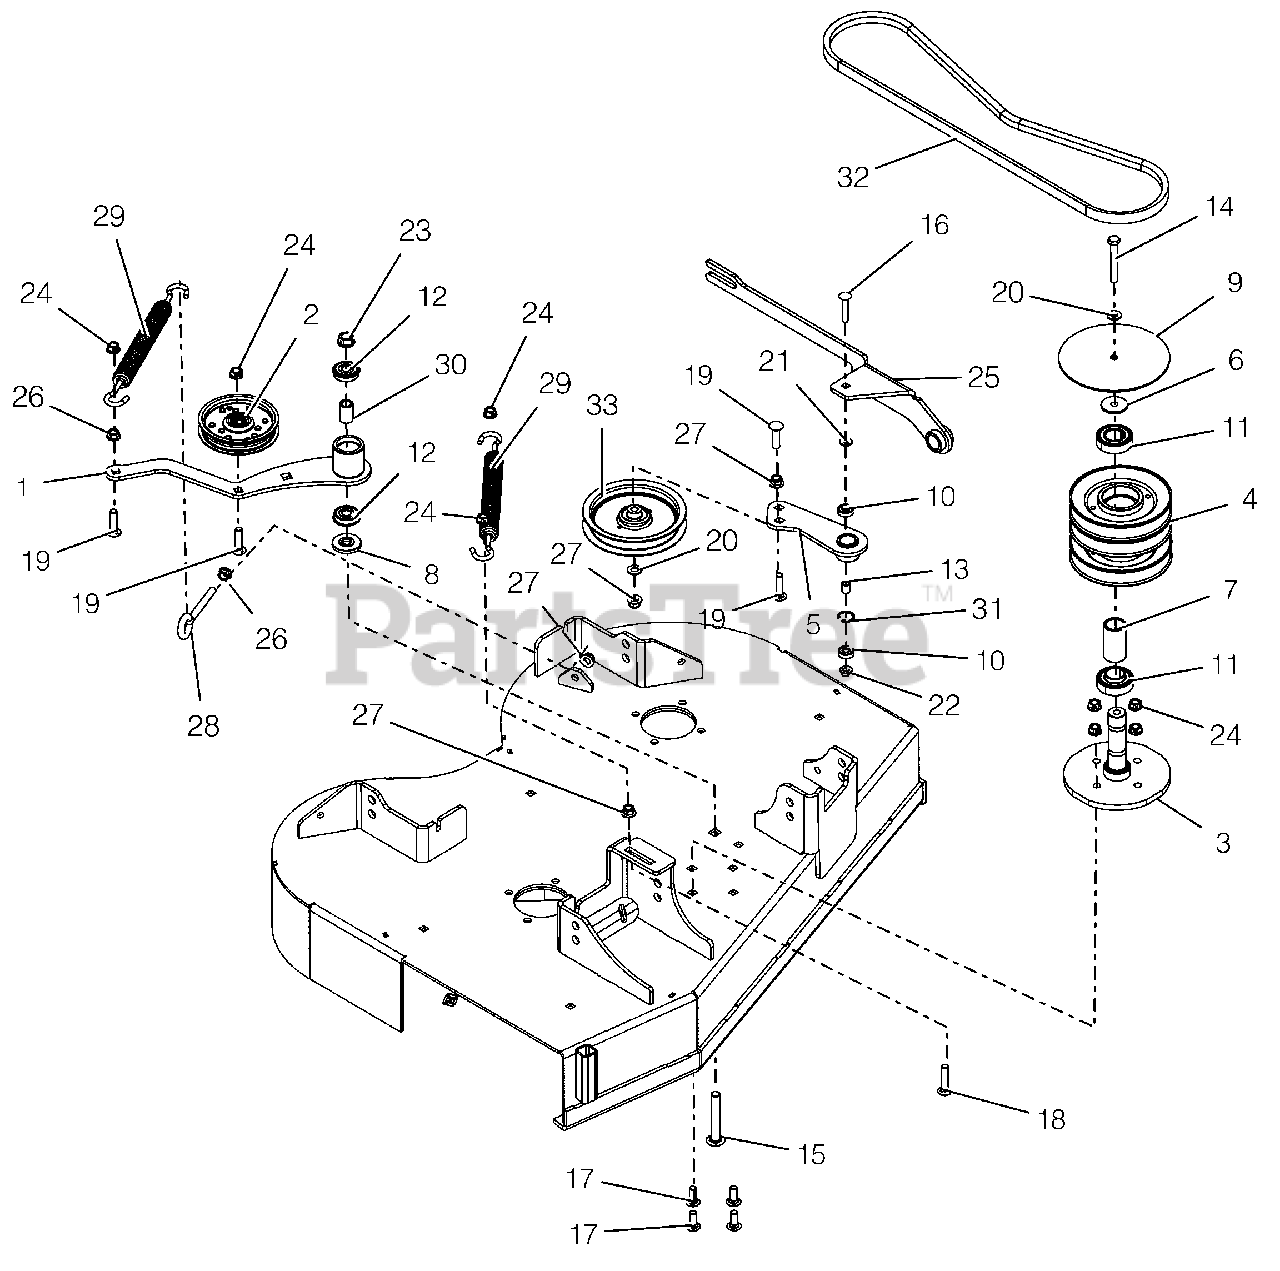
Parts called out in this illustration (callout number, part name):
1	WLDMT, IDLER ARM
2	ASM, 4" IDLER (.75 WIDE)
3	WLDMT, JACKSHAFT SHAFT
4	WLDMT, JACKSHAFT HOUSING
5	WLDMT, DECK IDLER
6	RETAINER, JACKSHAFT SPINDLE
7	SPCR, BEARING SPINDLE
8	SPACER, IDLER ARM
9	PLATE, JACKSHAFT COVER
10	BRG-BALL .315X.866X.276(608)
11	BEARING, RG 1.00X2.0467X.591
12	BRG-BALL .50X1.38X.438 SEALED
13	BSHG-SLV .330X.455X.550
14	BLT-HEX .38-16X2.75 GR8 YWZC
15	BLT,RDHDSQSHNK.50-13X3.25 G5YZ
16	@BLT-RDHDSQNK .31-18X1.75 G5YZ
17	@BLT-RDHDSQNK .38-16X1.00 G5YZ
18	@BLT-RDHDSQNK .38-16X1.75 G5YZ
19	@BLT-RDHDSQNK .38-16X1.50 G5YZ
20	@WSHR-FL-STL.406X.812X.065 YWZ
21	@WSHR-FL-STL.344X.688X.065YWZC
22	@NUT-LK-CTR-FLG .31-18 YZ GR F
23	NUT-LK-CTR-FLG .50-13 YWZC
24	NUT-LK-CTR-FLG .38-16 YWZC
25	WLDMT, PIVOTING IDLER
26	@NUT-SPNLK-FLG .375-16 YWZC
27	@NUT-LK-NYL-FLG .38-16 YWZC
28	BOLT,EYE .38-16X4.50,.75"EYE
29	SPRING, EXTENSION
30	SPACER .510 X .75 X 1.1485
31	RING, RETAINING 7/8" INT
32	BELT, 5L RAW EDGE
33	IDLER, FLAT-5.00X.75
